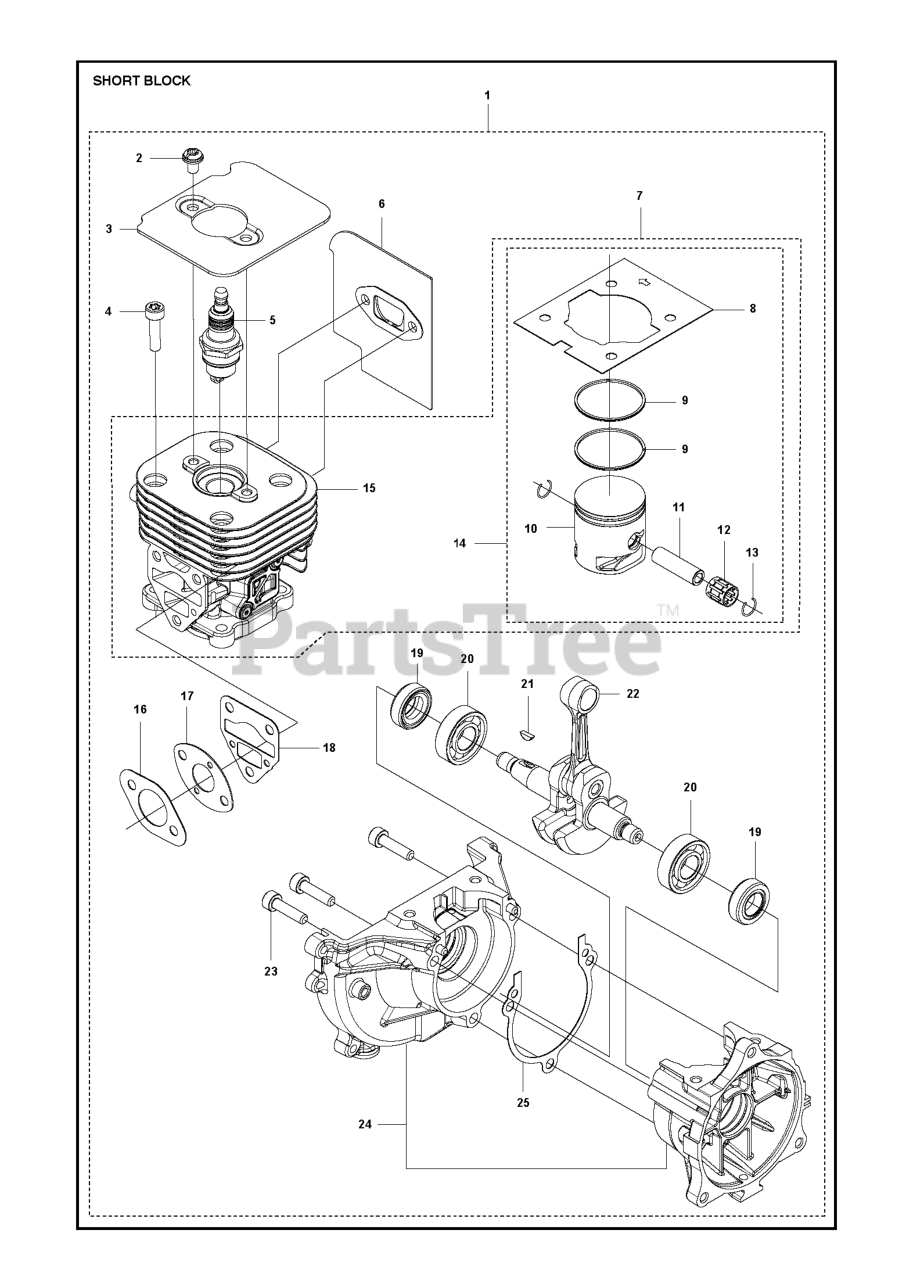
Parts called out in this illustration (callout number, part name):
1	SHORTBLOCK
3	PLATE CYLINDER
4	BOLT
5	SPARK PLUG NGK BPMR-8Y
6	GASKET MUFFLER
7	SERVICE KIT
8	GASKET BASE
14	SERVICE KIT PISTON 525 TRIMMER
15	CYLINDER COMP
17	GASKET CARBURETOR
22	CRANKSHAFT COMPLETE
23	BOLT
24	CRANKCASE COMP
25	GASKET CASE
